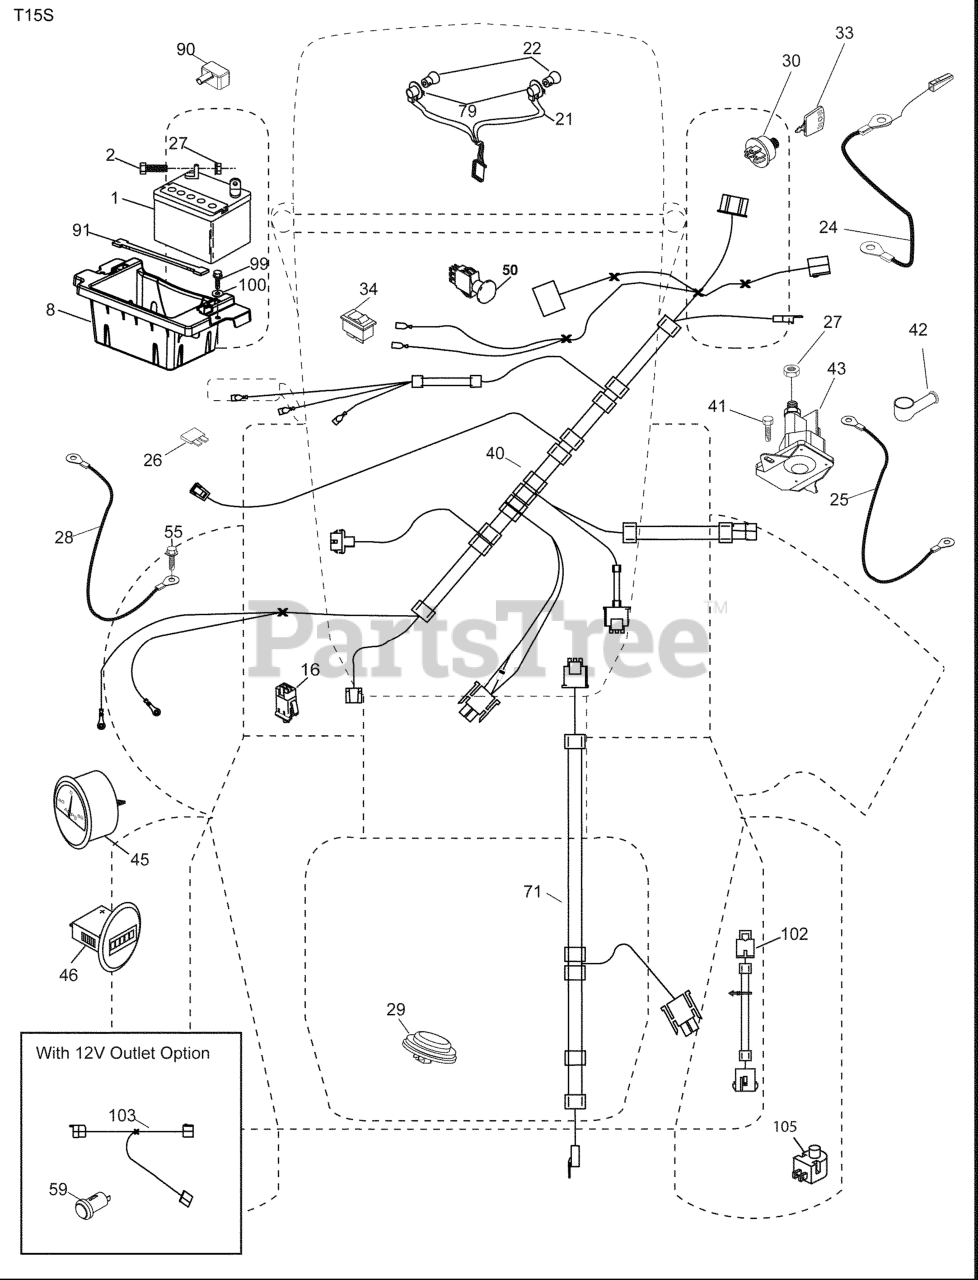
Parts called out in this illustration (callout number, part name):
1	Battery
2	BOLT.HEX.1/4.X.3/4.DICHROMATE
8	BOX.BATTERY.MOUNT.FRONT.LT
16	SWITCH INTERLOOK PUSH-IN
21	HARNESS ASSY LIGHT
24	CABLE.BATT.POS.WIRE.TG.DA SOL
25	CABLE.STARTER.6G.BL/RED.17.5
26	FUSE 20AMP
27	NUT
28	CABLE GROUND 6 GA 21" 90T BLK
29	SWITCH.SEAT.DELTA.OPC.
30	SWITCH.IGN.DELTA.W.LGH.ROS
33	KEY.CHAIN.BLISTER.PACK.GEN.INT
40	HARNESS IGN. DASH
41	SCREW
42	TERMINAL COVER
43	SOLENOID.W/BRASS.PLUNGER
45	AMMETER GAUGE ROUND SNAP-IN
46	HOURMETER.GAUGE.RNK.SNAP.LS
50	RP.PTO.SWITCH.8 TERMINAL.BLACK
55	SCREW 5/16"
59	OUTLET.12-VOLT
71	HARNESS-CHASSIS SUB
79	BULB HOLDER ASM.
90	COVER.TERMINAL.BATTERY
91	STRAP.BATTERY.MOUNT.FRONT(2 2)
99	SCREW HEXWSHR 1/4-20X3/4
100	WASHER
102	HARNESS PIGTAIL PCH TEX ROS
103	HARNESS.PIGTAIL.12V.OUTLET.
105	REVERSE SWITCH
